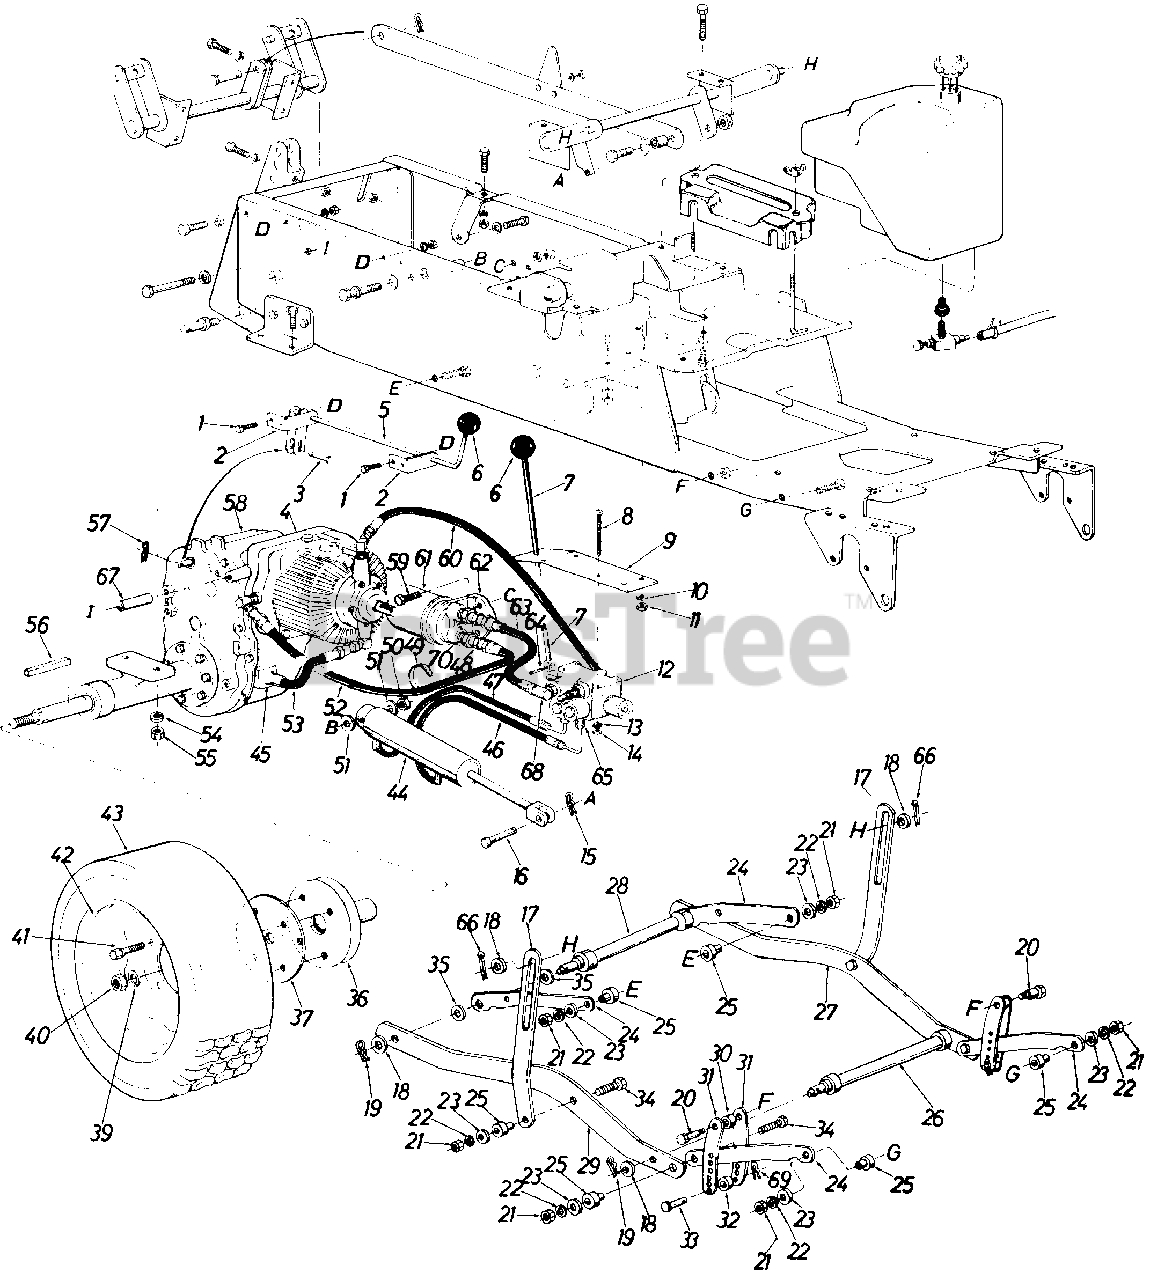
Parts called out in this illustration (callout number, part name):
1	Hex Scr. 1/4-20 x .75" Lg.
4	Hydrostatic Pump Comp.
5	Hi-Lo Control Handle Ass'y.
6	Ball Knob
7	Cylinder Control Handle Ass'y.
8	Truss Mach. Scr. 1/4-20 x 3.00" Lg.*
11	Hex Nut 5/16-18 Thd.
12	Valve Ass'y. Comp.
13	L-Wash. 1/4" Scr.
14	Hex Nut 1/4-20 Thd.
15	Hairpin Cotter 1/2" Dia.
16	Clevis Pin 1/2" Dia.
19	Hairpin Cotter
20	Shld. Scr. .498 Dia. x .66
21	Hex Nut 3/8-24 Thd.*
22	L-Wash. 3/8" Scr. H.D.
23	Fl-Wash. .38 I.D. x 1.00" O.D.
26	Cross Shaft Ass'y. Front
33	Clevis Pin 3/8" Dia.
34	Hex Scr. 3/8-24 x 1.50" Lg. Grade 5
35	Fl-Wash. .62" I.D. x 1.25" O.D. x .020
39	L-Wash. 3/4" Scr.
40	Hex Ins. L-Nut 3/4-16 Thd.
41	Wheel Lug Bolt 1/2-20 x 1.50" Lg.
44	Hydraulic Cylinder
45	7/8-14 UNF-2A Thd. 5/8 Tube Fitting
46	Valve to Cylinder Hose 20" Lg.
47	Valve to Cylinder Hose 20" Lg.
48	Bushing Reducer 1/2-14 NPTF to 3/8-18 NPTF
49	Cable Tie
50	Hex Jam Nut 1/2-20 Thd.
51	Fl-Wash. .50" I.D. x 1.25 O.D.
52	Filter Return Hose 24" Lg.
53	Pump Tube Ass'y.
54	L-Wash. 3/8" Scr.
55	Hex Nut 3/8-16 Thd.*
56	Sq. Key 1/4" x 1/4" x 2.00" Lg.*
57	Hairpin Cotter 1/4" Dia.
58	Peerless Transaxle
59	Hex Scr. 5/16-18 x 1.25" Lg. *
60	Pump to Valve Hose
61	Fram Fi Iter Ass'y. PH-16
62	Filter Base
63	Valve to Filter Hose 8.38" Lg.
64	Spring Pin Spiral 118" Dia. x .81" Lg.
65	Flare Adapter
66	Cotter Pin 1/8" Dia. x 1.00" Lg. *
67	Spacer
68	Adapter 9/16-18 to 9/16-18
69	Hairpin Cotter
70	Reducer 1/2-3/8 NPT
